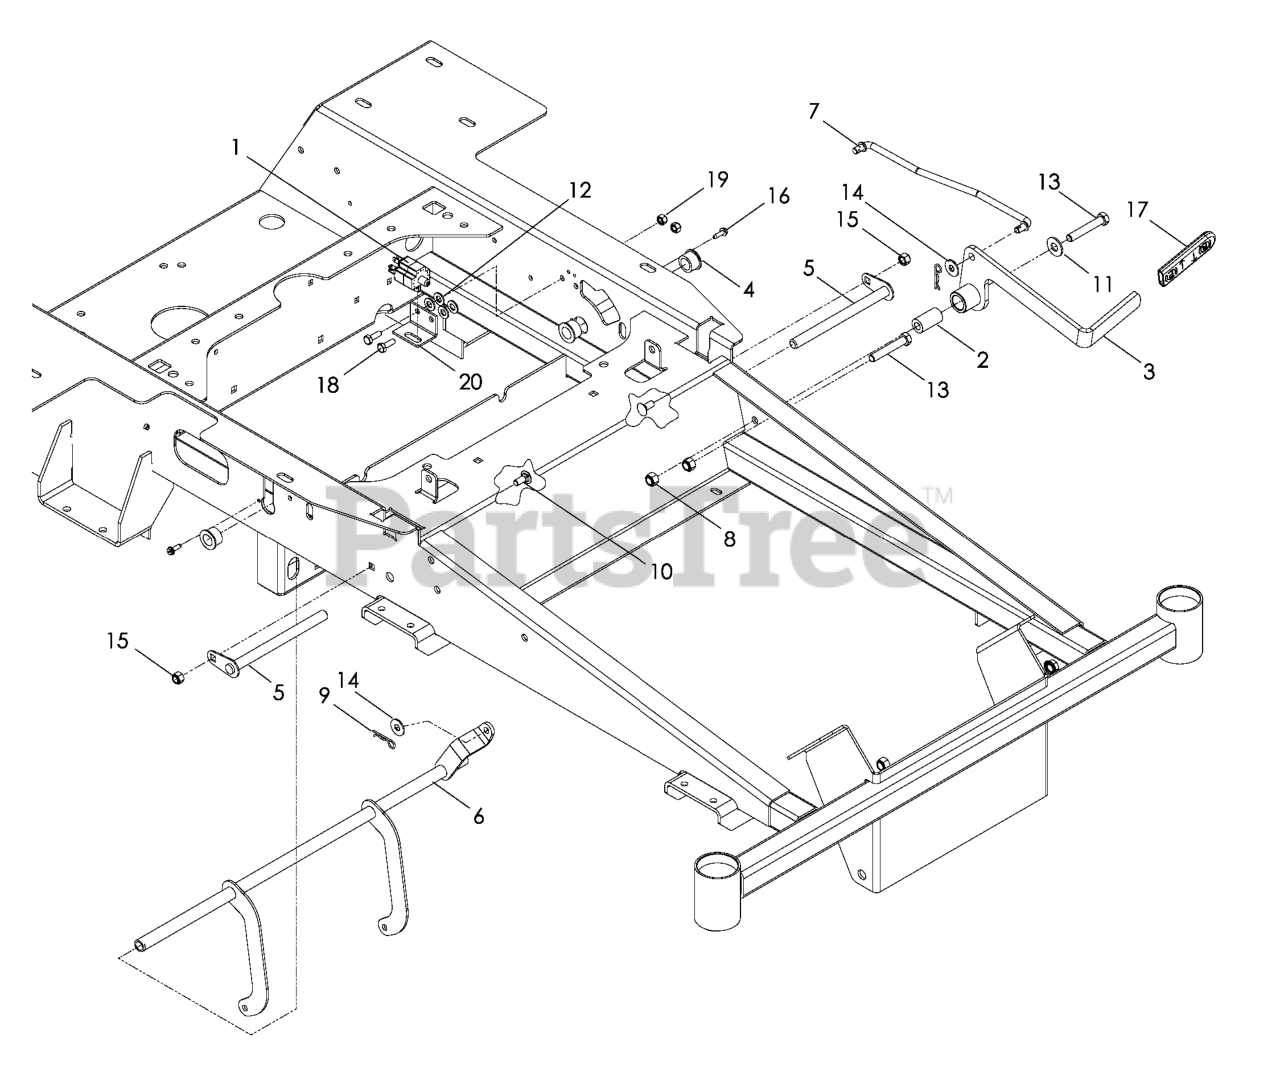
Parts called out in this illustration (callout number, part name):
1	SWITCH, BRAKE 3P
2	BUSHING, SLEEVE
3	BRAKE LEVER WLDMT
4	PLASTIC BUSHING
5	PIVOT SHAFT
6	BRAKE SHAFT
7	BRAKE LINKAGE
8	NUT 3/8-16 NYLOC
9	HAIRPIN #2
10	BOLT 5/16C X 3/4" CARRIAGE
11	WASHER 3/8 FLAT
12	FLAT WASHER 5/16 SAE
13	HCS 3/8C X 2 1/4
14	WASHER 5/16 FLAT
15	NUT 5/16 NYLOC
16	SCREW #10 X 1/2 SELF TAPPING
17	GRIP, PARK BRAKE
18	HCS 1/4C X 3/4 HCS
19	NUT.1/4-20.HEX.NYLOC.ZD
20	BRACKET, BRAKE SWITCH
